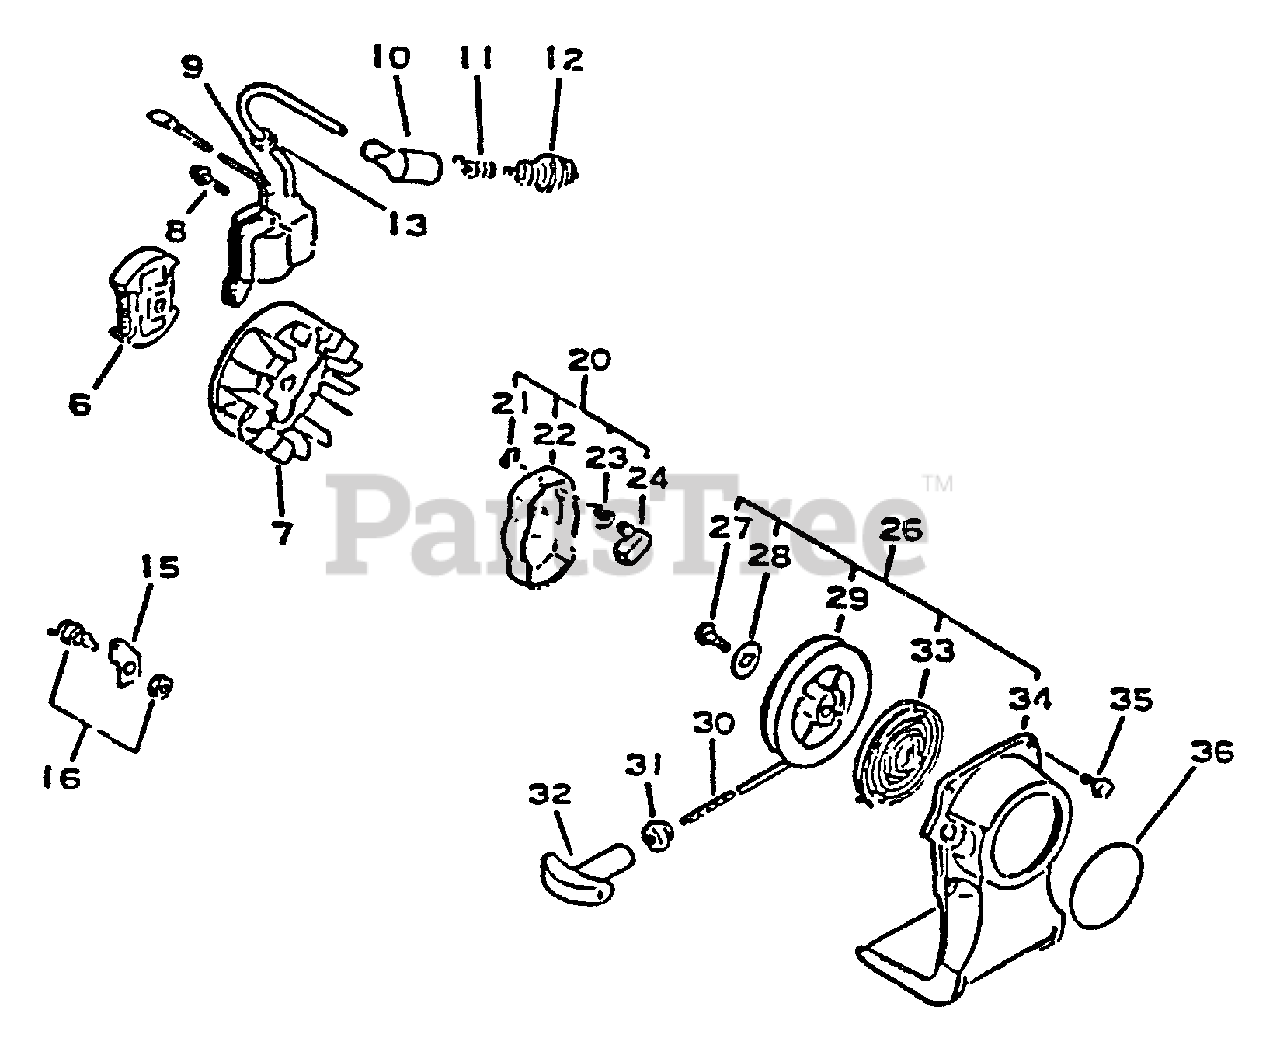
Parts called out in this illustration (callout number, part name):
6	Clutch Assembly
7	Flywheel
8	Screw 4=22
9	Coil, Ignition
10	Cap, Spark Plug
11	Coil, Spark Plug Cap
12	Plug, Spark (BPH-7A)
13	Bushing
15	Bracket, Switch
16	Switch, Ignition
20	Pawl, Ash., Starter
21	E-Ring 4
22	Catcher, Pawl
23	Spring, Return
24	Pawl, Starter
26	Starter Assembly
27	Screw 4=22
28	Washer
29	Drum, Starter
30	Rope, Starter
31	Guide, Rope
32	Grip, Starter
33	Spring, Rewind
34	Case, Starter (BL)
35	Screw 4=16
36	Label, Echo
